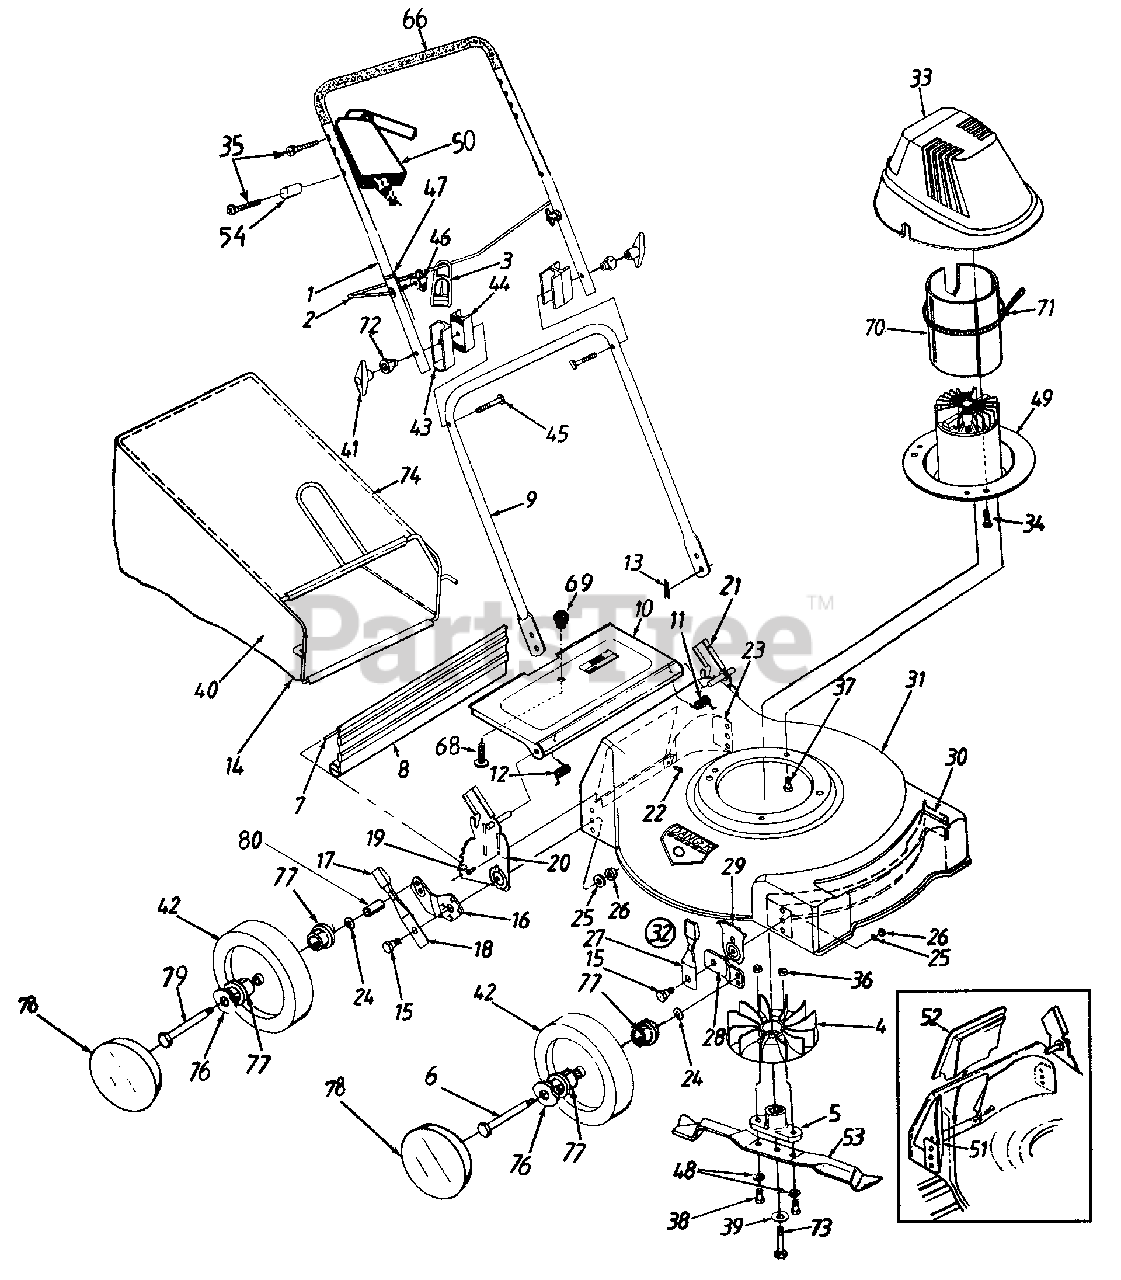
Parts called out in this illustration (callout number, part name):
3	Strain-Relief Cord
5	Blade Adapter
6	Axle Bolt
7	Rear Flap Wire
8	Rear Flap
12	Door Spring (R. H.)
13	Hairpin Clip
16	Pivot Bar (R.H.)
17	Spring Lever Knob
18	Spring Lever
19	Hex AB-Tap Scr.
20	Handle Bracket Ass'y. (R.H.)
21	Handle Bracket Ass'y. (L.H.)
22	Torx. Mach. AB-Tap Scr.
25	Bell Washer .39" I.d. x 1.38"o.d.
26	Hex Nut 3/8-16 Thd.
27	Spring Lever Ass'y. W/ Knob
29	Height Adj. Plate
33	Motor Cover
34	Scr. #10-24 x .75" Lg.
35	C-Sunk Scr.1/4-20 x 1.8" Lg.
36	Hex Nut 3/8-24 Thd.
37	Hex Tt-Tap Scr. 3/8-16 x 1" Lg.
38	Hex Bolt 3/8-24 x 1.25" Lg.
39	Bell Washer .396" I.d. x 1.14"
40	Grass Bag w/o Icon
41	Plastic Knob
42	Wheel Ass'y Comp. 8" X 1.75" Bar
42	Wheel Ass'y Comp. 7" x 1.50" Diamond
42	Wheel Ass'y Comp. 8" x 1.70" Aero Grey Bar
42	Wheel Ass'y Comp. 8" x 2.00" Link
43	Upper Handle Insulator
44	Lower Handle Insulator
45	Carriage Bolt 5/16-18 x 3" Lg.
47	Cable Tie
48	Bell Washer 3/8" I.d.
49	Motor, Cord & Switch Ass'y.
50	Cord & Switch Ass'y. Comp.
53	19" Mulching Blade
54	Spacer
66	Foam Grip
68	Truss Scr. #10-24 x .38" Lg.
70	Cable Tie
71	Insulator Motor Hsg.
72	Insulator Knob
73	Hex Bolt 3/8-24 x 2.5"
77	Ball Bearing
78	Hub Cap Euro - Grey
78	Hub Cap Black - Moon
78	Hub Cap Radial Spoke - Grey
78	Hub Cap Radial Spoke - Beige
79	Rear Axle Bolt
80	Spacer
